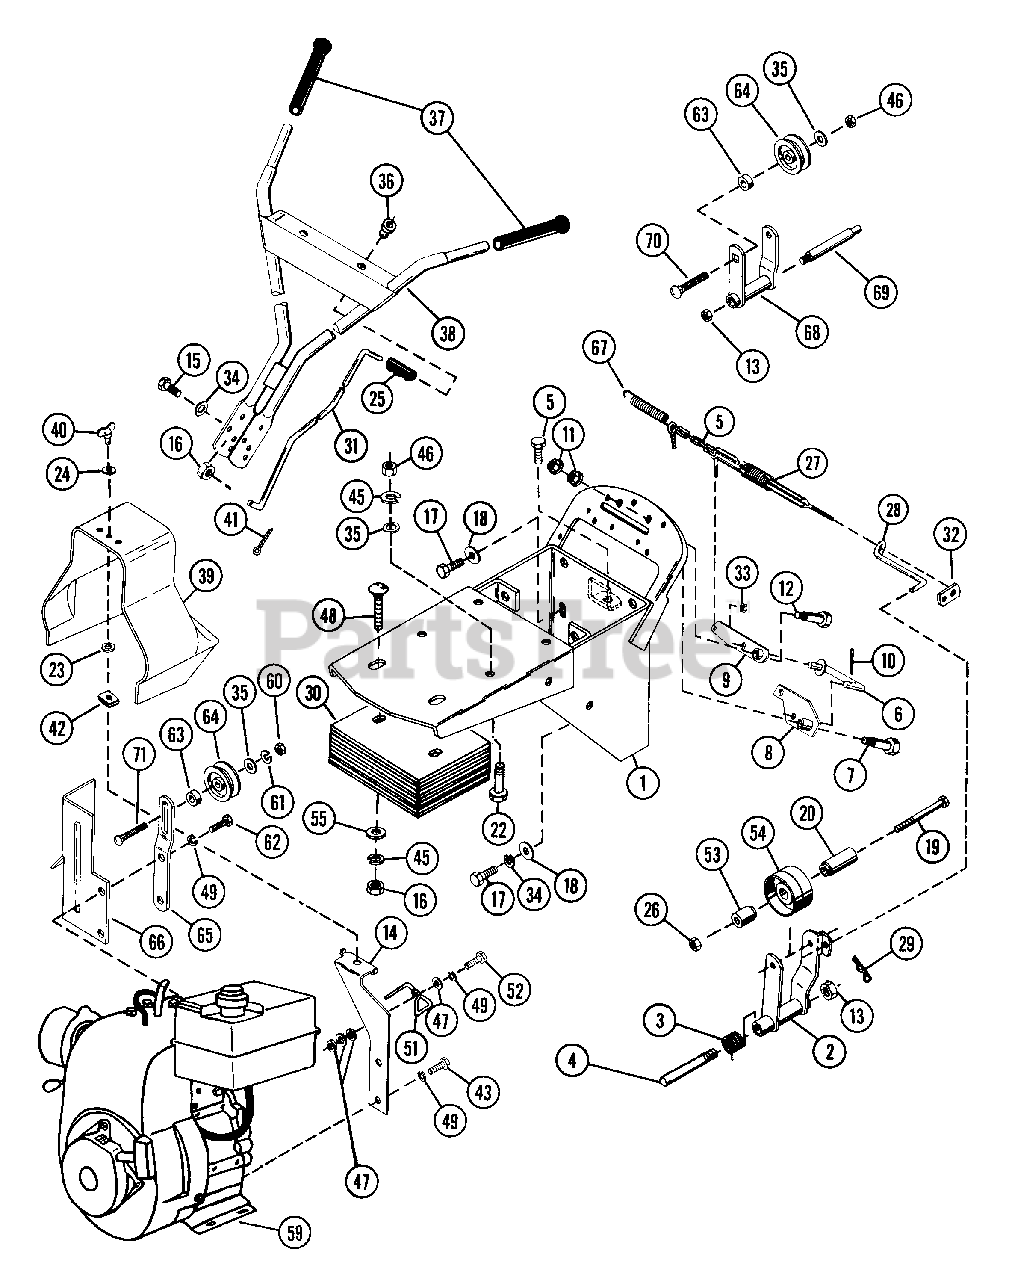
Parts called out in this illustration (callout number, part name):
2	IDLER ARM
3	SG-TORS .076X.89X1.98
4	IDLER PIN
5	BLT-HEX .31-18X1.00 PL GR 2
6	CLUTCH LINK
7	SHOULDER BOLT
8	CLUTCH BELLCRANK
9	SPRING ARM
10	PIN-COTR .09X1.0 PL
11	NUT-LK-CTR .375-16 GR A PL
12	SHOULDER BOLT
13	NUT-LK-FLG .375-16 PL
14	BELT COVER BRACKET
15	BLT-HEX .38-16X1.00 PL
16	NUT-HEX .375-16
17	BLT-HEX .38-16X1.25 PL GR 2
18	WSHR-FL-STL.406X.812X.065PL
19	BLT-HEX .31-18X3.75 PL GR2
20	SPACER-SHOULDER
22	BLT-HEX .31-18X1.00 PL GR 2
23	NUT-RETNR
24	WSHR-FL-STL .250X.562X.049 PL
25	GRIP
26	NUT-LK .312-18 GR A PL
27	CLUTCH SPRING
28	CLUTCH LINK
29	PIN-HAIR INT .06X.18X.77
30	WEIGHT WAFER
31	CLUTCH ROD
32	RETAINING NUT
33	NUT-LK 8-32 GR A PL
34	WSHR-LK .375X.115 HVY PL
35	WSHR-FL-STL .38X.875X.083 PL
36	SNAP BUSHING
37	HANDLEGRIP
38	HANDLEBAR
39	BELT COVER
40	SCR-WING .25 TURN SOUTHCO
41	PIN-COTR .09X.75 PL
42	NUT-SPEED 1/4 TURN SOUTHCO
43	BLT-HEX .31-24X.50 GR5
45	WSHR-LK .375X.094 MED PL
46	NUT-LK .312-18 GR A PL
47	WSHR-FL-STL .323X.625X.062 PL
48	BLT-RDHDSQNK .38-16X3.25 PL
49	WSHR-LK-INT .313X.030 PL
51	FORWARD BELT FINGER
52	BLT-HEX .31-24X1.00 PL GR5
53	SPACER .328X.625X.843
54	IDLER-FLAT 2.25 X .38
55	WSHR-FL-STL .630X1.005X.062 PL
59	ENGINE
60	NUT-HEX .312-18
61	WSHR-LK .312X.097 PL HVY
62	BLT-HEX .38-16X.75 PL GR2
63	BEARING SPACER
64	IDLER
65	REVERSE IDLER BRACKET
66	HEAT SHIELD
67	SG-TENS .039X.44X1.75 WLD 3.2
68	IDLER ARM
69	IDLER PIN
70	BLT-RDHDSQNK .31-18X1.38SHT PL
71	BLT-RDHDSQNK .31-18X1.75 SHTPL
